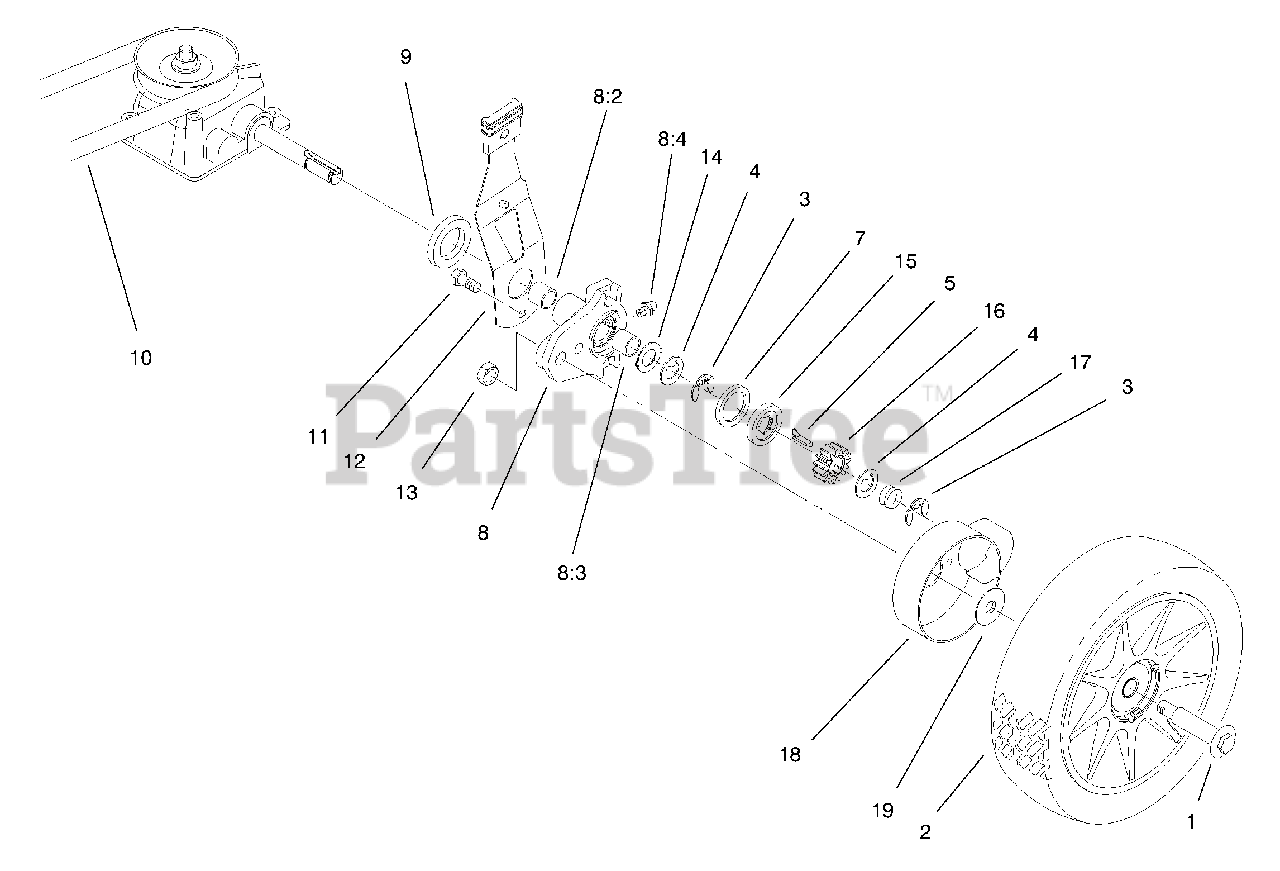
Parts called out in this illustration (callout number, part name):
1	Bolt-Shoulder
3	Ring-Retaining
4	Washer-Thrust
5	Key-Rocking LH
6	Key-Locking RH
7	Ring-Friction
8	ASM-Hgt Adj Arm
8:4	Fitting-Grease
9	Spacer-Axle Shaft
12	ASM-Spring Arm
13	Nut-Lock
14	Washer-Thrust
16	Gear-Pinion
17	Spring-Compression
18	Cover-Wheel
19	Washer-Stepped
